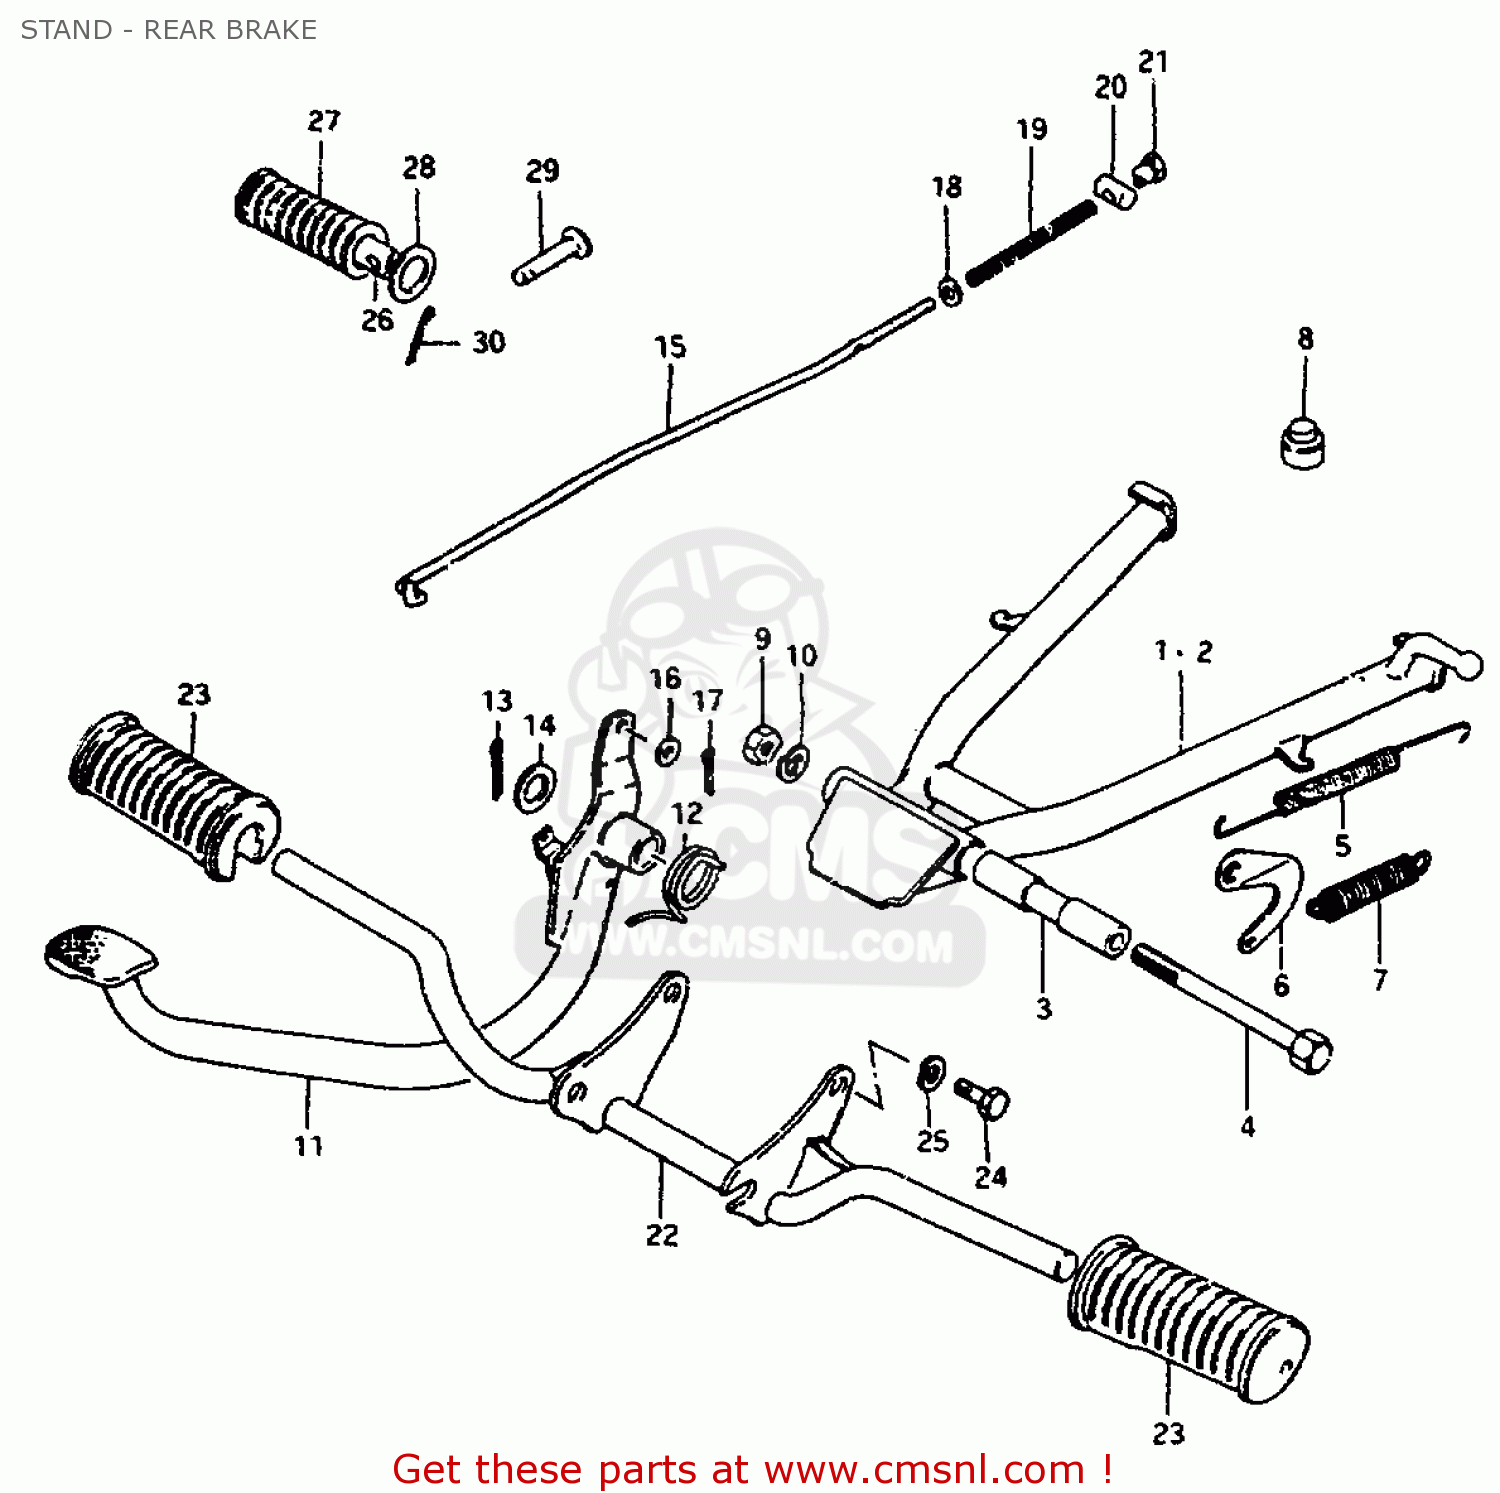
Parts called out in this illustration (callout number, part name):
1	STAND, CENTER
3	SPACER
4	BOLT(10X110)
5	SPRING
8	CUSHION
9	NUT
10	LOCK WASHER
11	PEDAL, BRAKE
12	SPRING
13	COTTER PIN
14	WASHER(15.5X26X2.3)
15	ROD ASSY,RR BRAKE
16	WASHER
17	PIN 20X20
18	WASHER
19	SPRING
20	PIN(11X18)
21	NUT
22	BAR, FRONT FOOTREST
23	RUBBER,FR FOOTREST
24	BOLT
25	LOCK WASHER
26	BAR,FOOTREST RUBBER
27	RUBBER,PILLION FOOTREST
28	WASHER (19.5X32X2)
29	PIN
30	PIN 20X20
